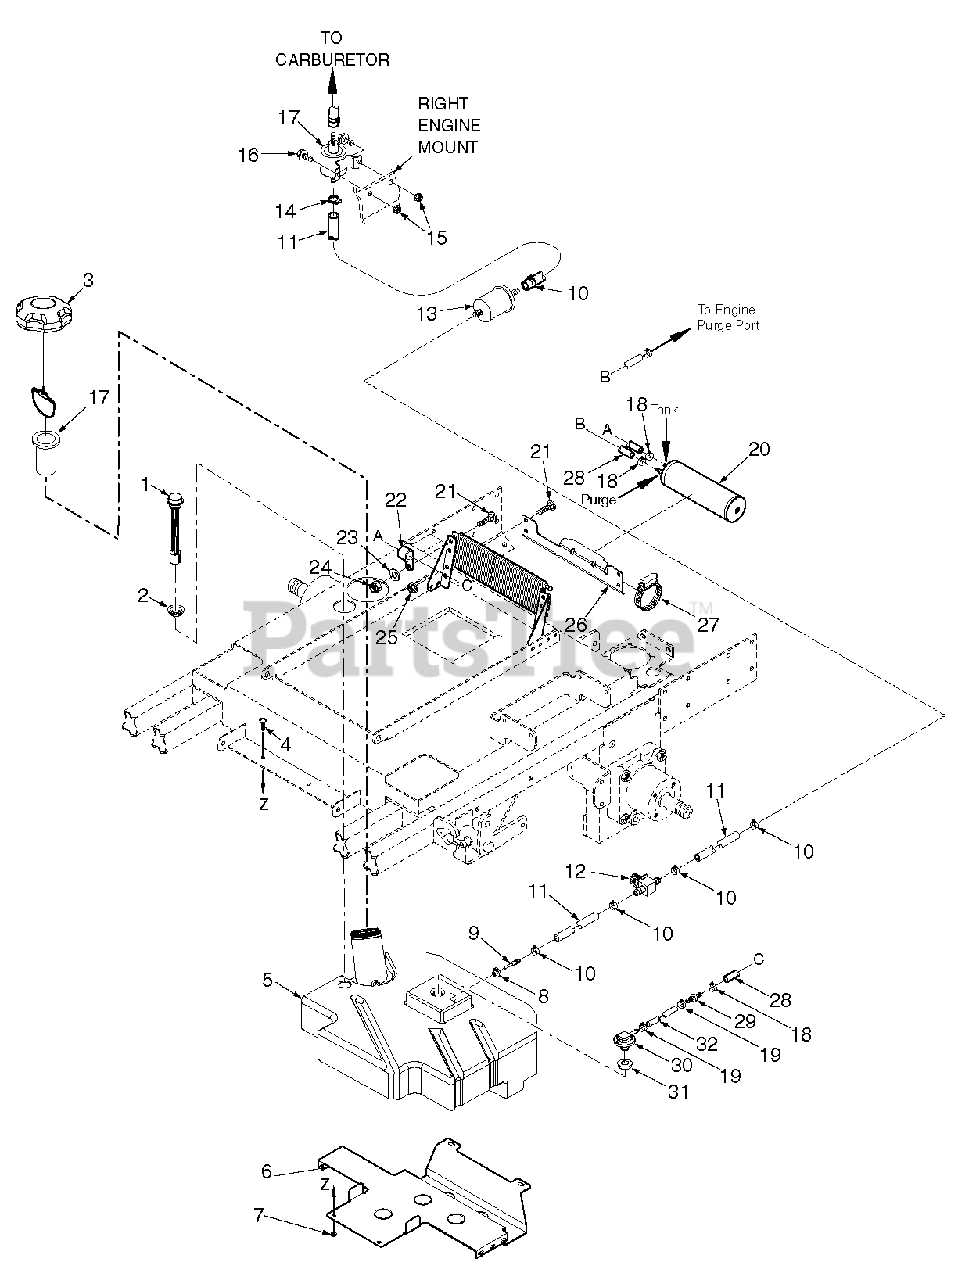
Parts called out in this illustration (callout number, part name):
1	Fuel Gauge Assembly
2	Seal, Fuel Gauge
3	Fuel Cap, Tethered
4	Bolt, Carriage 1/4-20 x 3/4"
5	Fuel Tank Assembly, Low Perm. - STT
6	Support Bracket, Fuel Tank
7	Nut, 1/4-20 Serrated Flange
8	Bushing, .56 Dia. Viton
9	Hose Fitting
10	Clamp, Fuel Hose 5/16" I.D.
11	Fuel Hose, 5/16" I.D. Non-Perm (791DFI) - Order by Inch
12	Valve, Fuel Shut-Off
13	Fuel Filter, Kubota
14	Hose Clamp, 0.69 Dia.
15	Nut, Elastci Stop 1/4-20
16	Bolt, Hex Head 1/4-20 x 3/4"
18	Clamp, Vapor Recovery Hose 3/16"
19	Clamp, Fuel Hose 7/32 ID
20	Carbon Canister
21	Bolt, Carriage 1/4-20 x 3/4"
23	Flatwasher, 1/4-.281 x .562 x .049
24	Nut, 1/4-20 Elastic Stop
25	Nut, 1/4-20 Serrated Flange
26	Bracket, RH Canister Mounting
28	Hose, 3/16
29	Mender, 1/4 x 3/16 w/.02 Hole
30	Valve, Rollover
31	Grommet, Viton
32	Hose, 1/4" Vapor Recovery
